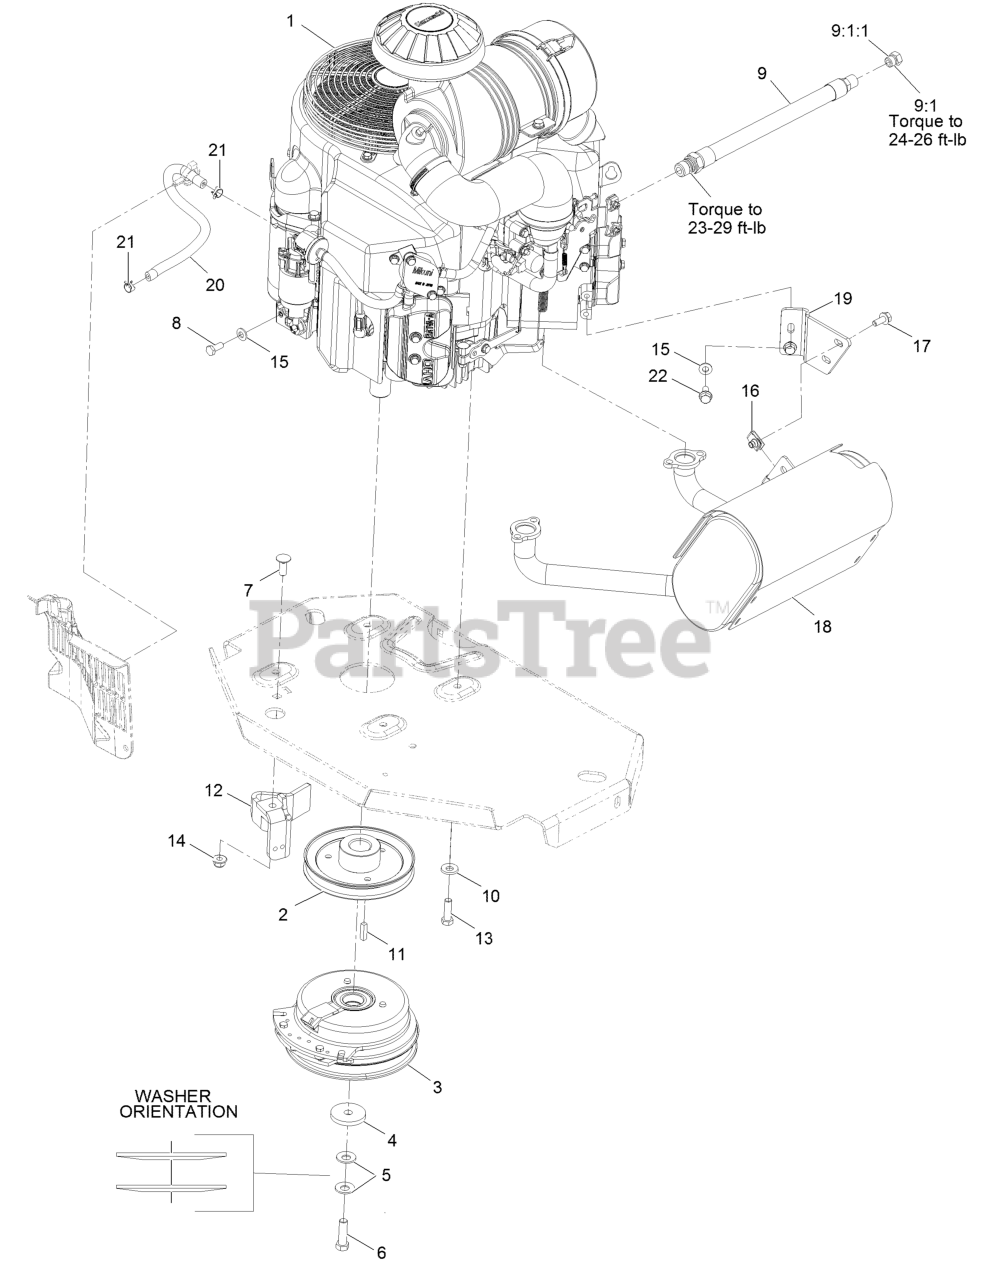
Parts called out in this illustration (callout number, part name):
1	PUMP IDLER ASM
2	Nut-Nyloc 3/8-16 Flg
3	LH HYDRO ASM (12CC W/ CHECK)
4	BELT
5	SPRING-EXTENSION
6	CRADLE-HYDRO
7	BOLT-SHOULDER, CARRIAGE 3/8-16 X 3 1/2
8	SCREW-CARR
9	Nut-Lock 1/2-13
10	SCREW-HH
11	RH HYDRO ASM (12CC W/ CHECK)
12	LH HYDRO GUARD ASM
12:2	DECAL-OIL, HYDRO
13	RH HYDRO GUARD ASM
13:2	DECAL-OIL, HYDRO
14	GUARD-HYDRO, REAR (LH)
15	GUARD-HYDRO, REAR (RH)
16	RIVET-POP
17	DEFLECTOR-AIR FLOW
